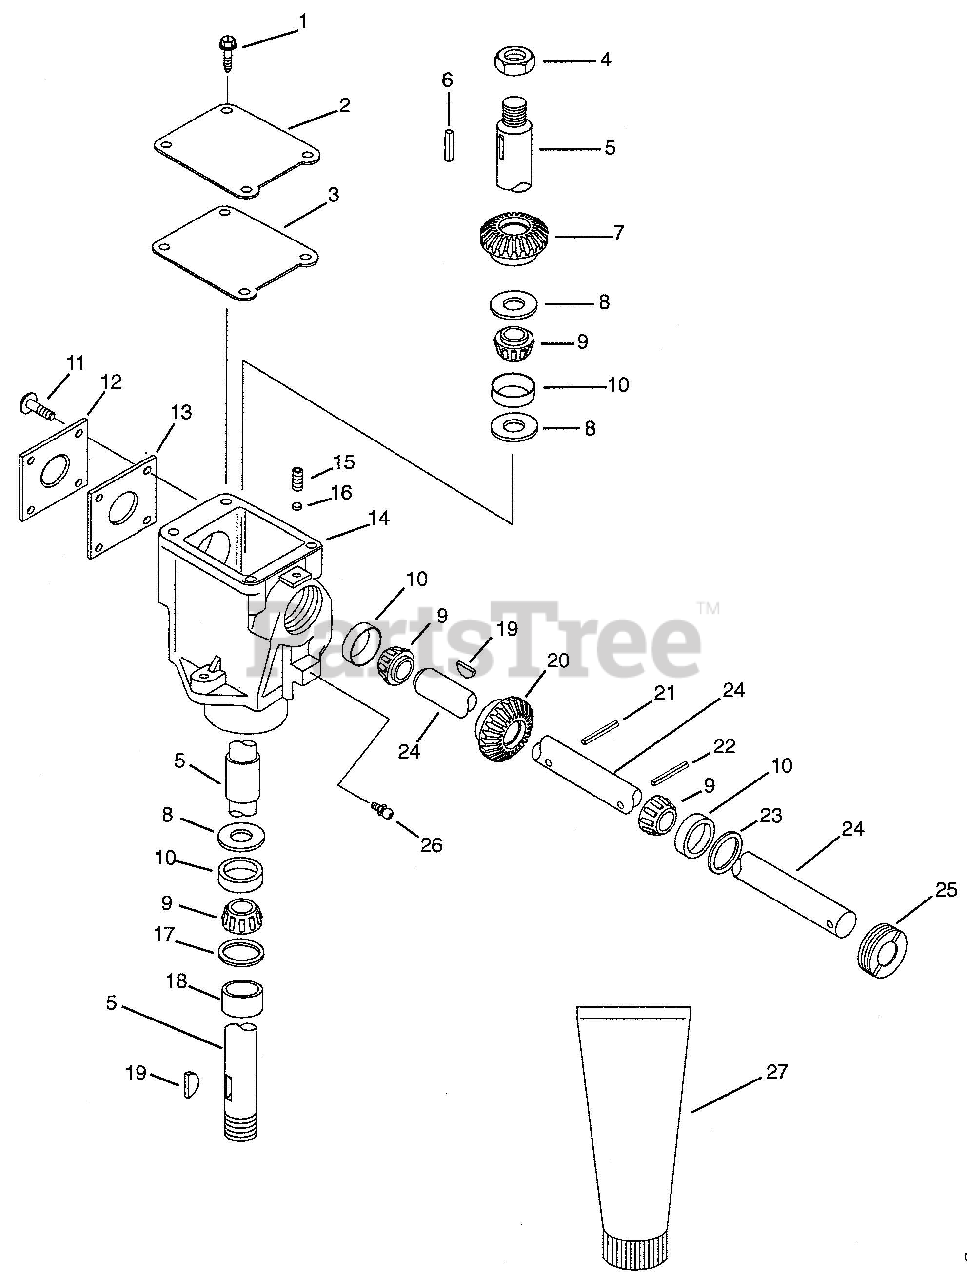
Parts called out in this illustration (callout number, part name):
1	SCREW-TAPPING 8-32 X .50
2	GEAR CASE COVER
3	TOP GASKET
4	NUT-JAM-COTTER .562-18
5	OUTPUT SHAFT
6	KEY-SQUARE .25 X .625 X 25
7	GEAR
7	GEAR-BEVEL
8	WASHER-FLAT-STEEL .781 X 1.000 X .025
8	WASHER-FLAT-STEEL .781 X 1.000 X .005
8	WASHER-FLAT-STEEL .781 X 1.000 X .003
8	WASHER-FLAT-STEEL .781 X 1.000 X .032
8	WASHER-FLAT-STEEL .781 X 1.000 X .015
9	BEARING-CONE .750 X .61
10	BEARING-CUP 1.781 X .475
11	SCREW-TAPPING .312-18 X .75
12	BEARING SIDE COVER
13	SIDE COVER GASKET SET
13	SIDE COVER GASKET
14	GEAR CASE
15	SCREW-SET .25-.20 X .25
17	SEAL 1.000 X 1.980 X .375
19	KEY-WOODRUF .25 X .75 X 5
20	GEAR
21	PIN-GROOVE .188 X 1.00
22	PIN-GROOVE .188 X 1.25
23	SEAL .750 X 1.499 X .225
24	INPUT SHAFT
25	ADJUSTMENT PLUG
26	FITTING-LUBE .25-28 X .256
27	GREASE - STENS
